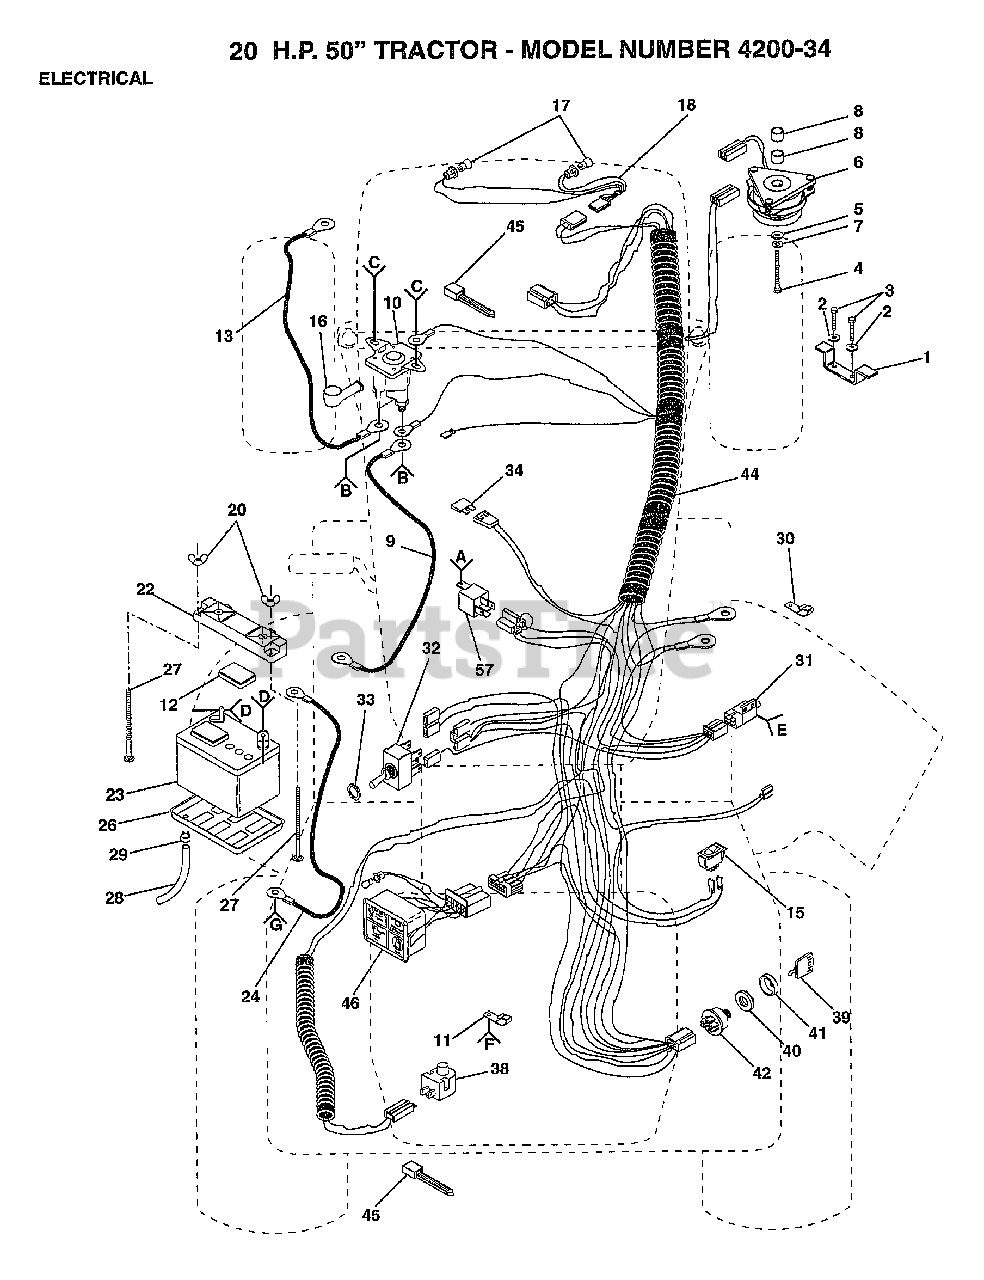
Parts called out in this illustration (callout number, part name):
2	LOCKWASHER
3	BOLT
5	WASHER
7	LOCKWASHER
8	SPACER-CLUTCH
9	CABLE-BATTERY T
12	"CAP,BATTERY "
13	"CABLE,STARTER T"
15	SWITCH LT
18	"HARNESS,LIGHT SOC"
24	CABLE T
26	"TRAY T, BATTERY"
27	BOLT
29	HOSE CLAMP T
30	CLIP GTV
31	SWITCH INTERLOCKT
33	HEX NUT T
34	FUSE HYT
38	SWITCH SEAT
39	KEY
40	NUT IGNITION
44	HARNESS.IGN
45	WIRE TIE
46	LIGHT.PKG.ASM.
57	RELAY ASSY T
